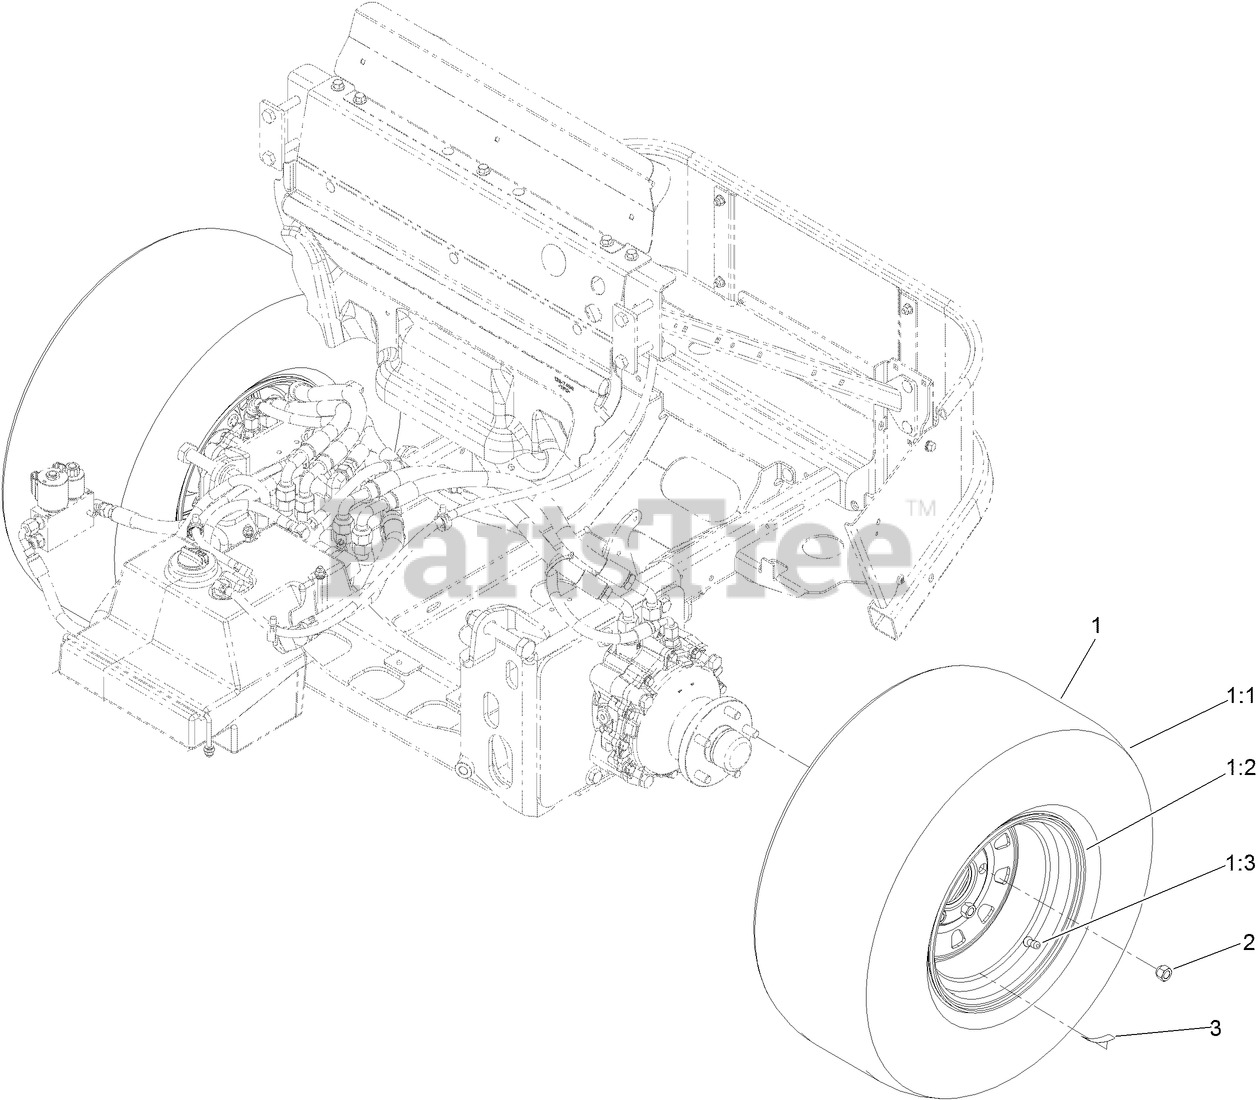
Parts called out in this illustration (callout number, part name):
1	TIRE ASM
2	NUT-LUG
3	DECAL-TORQUE, WHEEL NUT
